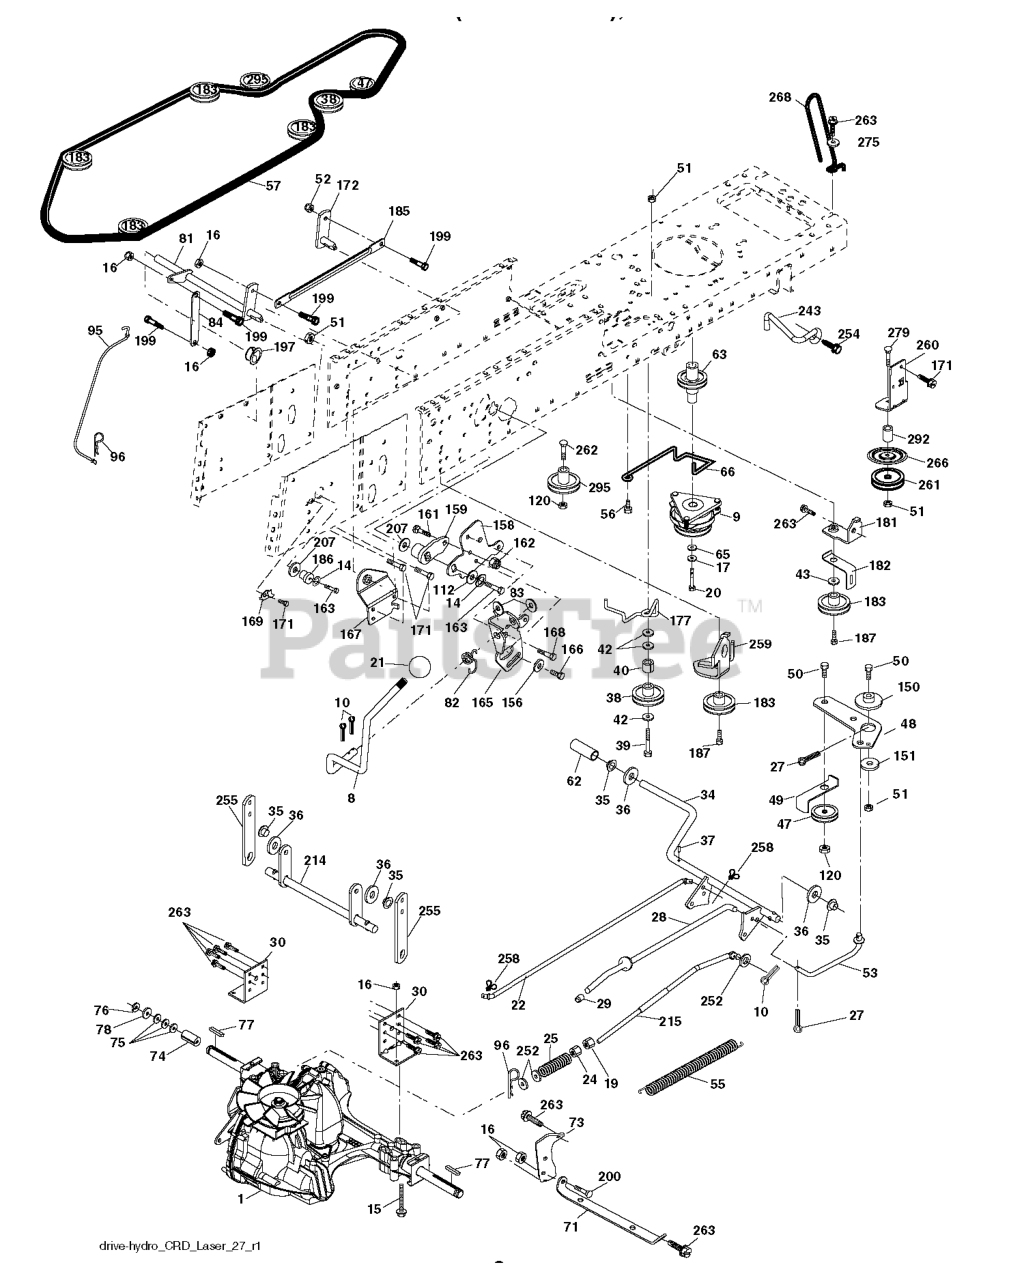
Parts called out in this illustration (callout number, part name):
8	ROD SHIFT FENDER ADJUST LT
9	CLUTCH.ELECTRIC.OGURA.EURO.
10	PIN COTTER
14	LOCKWASHER
15	BOLT HEX 5/16-18 GR 5
16	NUT.71038.31-18.HEX.NYLOCK
19	NUT
20	BOLT HEX 7/16-20X4-1/4"
21	KNOB.DUCKHEAD.1/2
22	ROD
24	NUT
25	SPRING BRAKE ROD
27	COTTER PIN
28	ROD, PARKING BRAKE
29	CAP
30	BRKT, TRNSXLE MNT 20"
34	SHAFT, FOOT PEDAL
35	BEARING.NYLON
37	DRIVE PIN
38	PULLEY.FLAT
42	WASHER
47	IDLER PULLEY
48	BELLCRANK, CLUTCH
49	RETAIN BELT
50	BOLT.3/8-16X1.50
52	LOCKNUT
53	LINK.CLUTCH.7.66.2005
55	SPRING, RETURN LT
56	SCREW.3/8-16
57	V-BELT 113"
62	PEDAL COVER T
63	PULLEY.ENGINE.CVX.LT
65	LOCKWASHER
66	KEEPER BELT ENGINE
71	STRAP TORQUE LH HYDRO
73	STRAP TORQUE RH HYDRO
74	SPACER AXLE
77	SQUARE KEY
81	ASM.CROSS.SHAFT.REAR.CRD.0510
82	SHIFT SPRING
83	WASHER
84	LINK.PNT.TRANSAXLE.0510.CRD
95	LINK
96	RETAINER M
120	NUT LOCK FLG 3/8-16 UNC
150	BUSHING.BELLCRANK.GRD.DR
151	WASHER 12/32X2X10GA
156	WASHER.SRRTD.5/16
158	BRACKET
159	RB HUB.SHIFT
161	BOLT
162	NUT.CROWNLOCK.1/4
165	RP BRACKET
166	CAPSCREW.HXHD.FLG.5/16-18X.625
167	BRACKET.SUPT.SHIFT.CRD
168	BOLT.SHOULDER.5/16-18X
169	PLATE.FASTENING.CROSS.SHAFT
172	LINK
181	BRACKET
182	BELT GUIDE
183	PULLEY.V-IDLER.GRND.DR
185	LINK
186	HUB.TAPERED.ROUND.CRD
187	BOLT.5/16-18X1.25
197	NYLINER SNAP 5/8" ID
199	BOLT SHOULDER 5/16-18 UNC
207	WASHER NYL
214	LEVER
215	ROD
243	BRACKET, ANTI-ROTATION
252	WASHER
254	SCREW 3/8-16X1
255	SHAFT
258	CLIP RETAINER
259	BRACKET
261	FLAT IDLER PULLEY
263	SCREW, 3/8-16X3/4
266	PROTECTOR
268	GUARD MUFFLER
275	WASHER
292	SPACER
295	PULLEY IDLER COMPOSITE
